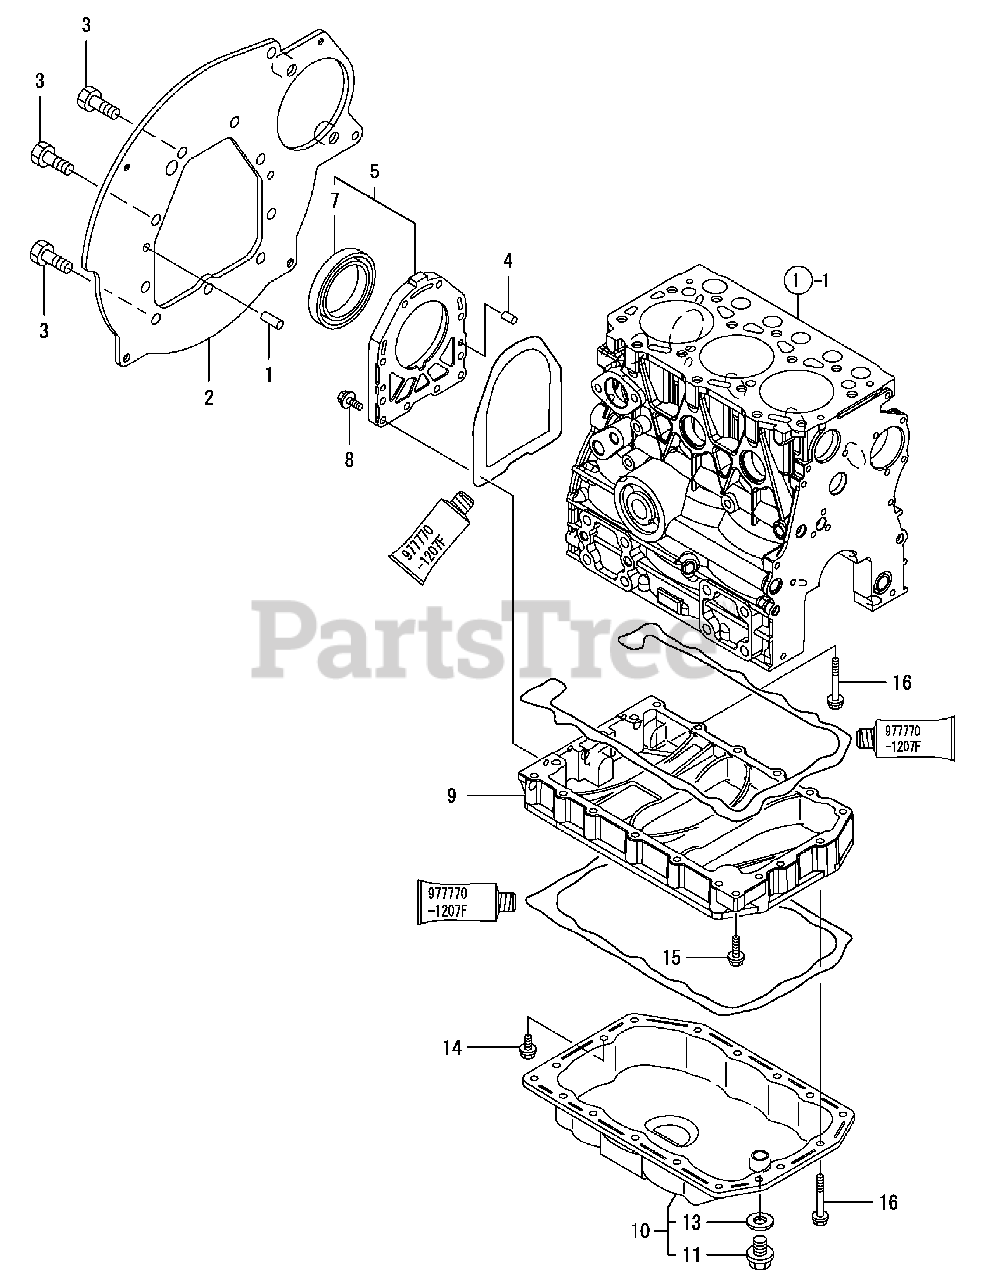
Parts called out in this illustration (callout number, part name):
1	PARALLEL PIN 8X16
2	FLANGE, MOUNT.
4	PARALLEL PIN 6X10
5	CASE ASSY, OIL SEAL
8	BOLT M 6X 22 PLATED
9	SPACER, OIL SUMP
10	SUMP ASSY, LUB.OIL
13	SEAL WASHER 12
14	BOLT M 6X 12 PLATED
15	BOLT M 6X 25 PLATED
16	BOLT M 6X 45 PLATED
